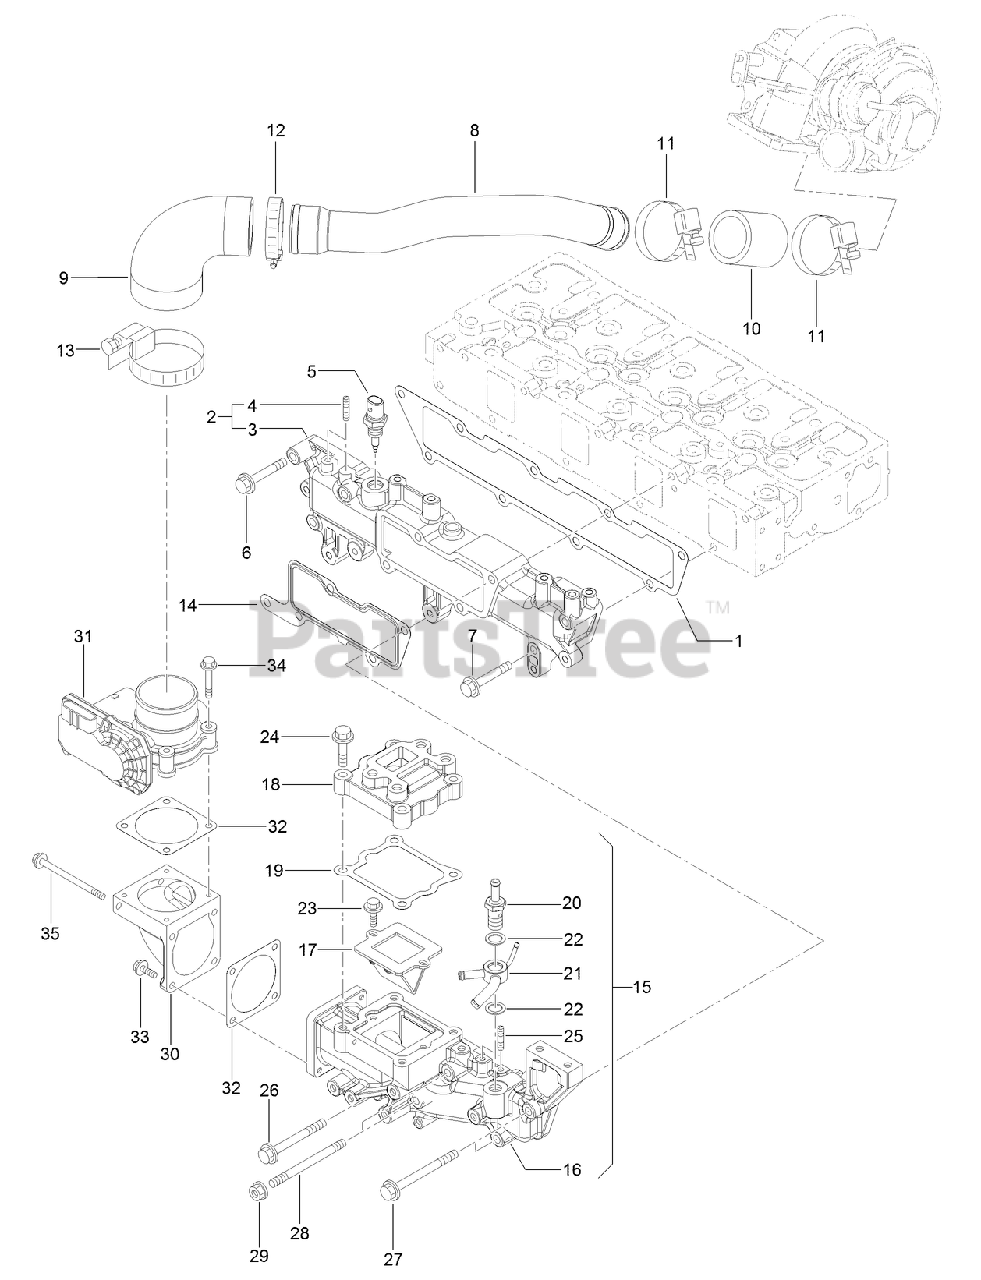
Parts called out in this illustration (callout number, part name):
1	GASKET-MANIFOLD
2	INTAKE MANIFOLD ASM
3	MANIFOLD-INTAKE, AIR
5	SENSOR-TEMPERATURE, AIR
8	DUCT-INTAKE
9	JOINT-RUBBER
10	JOINT-HOSE
11	CLAMP-HOSE
12	CLAMP-HOSE
13	CLAMP-HOSE
14	GASKET-COLLECTOR
15	COLLECTOR ASM
16	COLLECTOR
17	VALVE-REED
18	SPACER-VALVE, E G R
19	GASKET-V SPACER, E G R
20	JOINT-HOSE
21	JOINT-HOSE
22	WASHER-SEAL
30	BEND-INLET
31	BODY-THROTTLE
32	GASKET-THROTTLE
